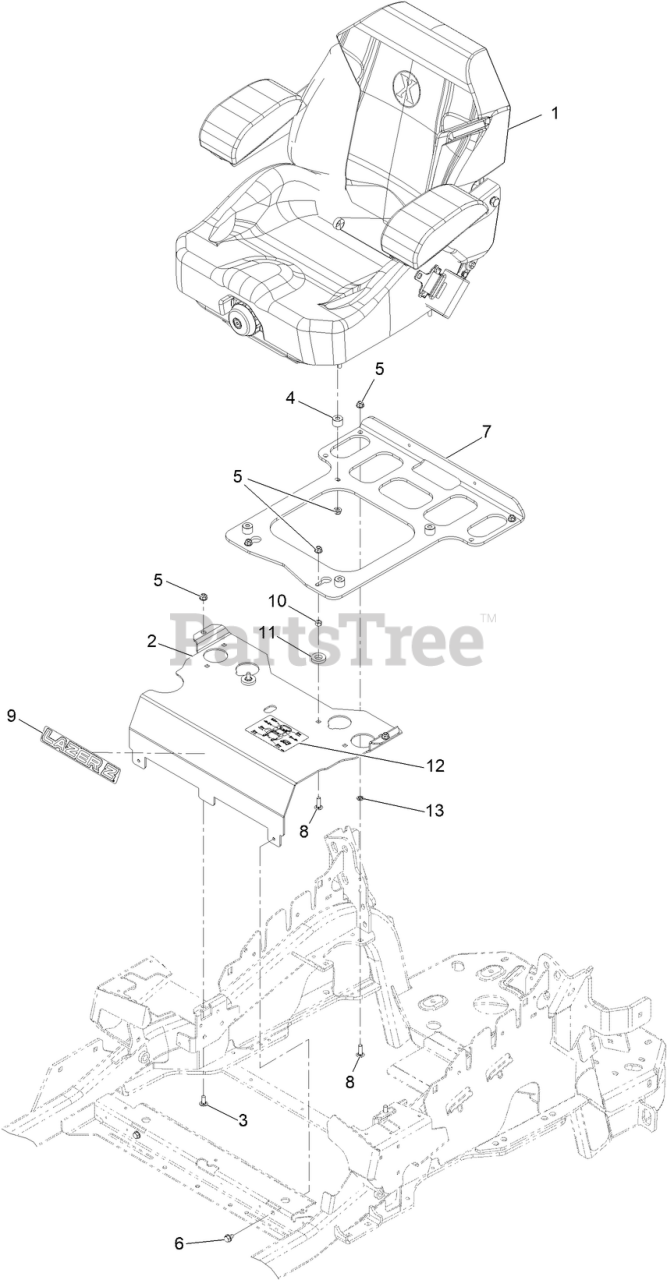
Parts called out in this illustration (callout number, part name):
1	KIT-SUSPENSION SEAT
2	Panel-Front, Seat Mount
3	SCREW-CARR
5	NUT-HF, NI
7	Plate - Support, Seat [black]
8	SCREW-CARR
9	DECAL, LAZER MODEL
10	NUT-HEX
12	DECAL-SERVICE AID
13	NUT-PUSH
